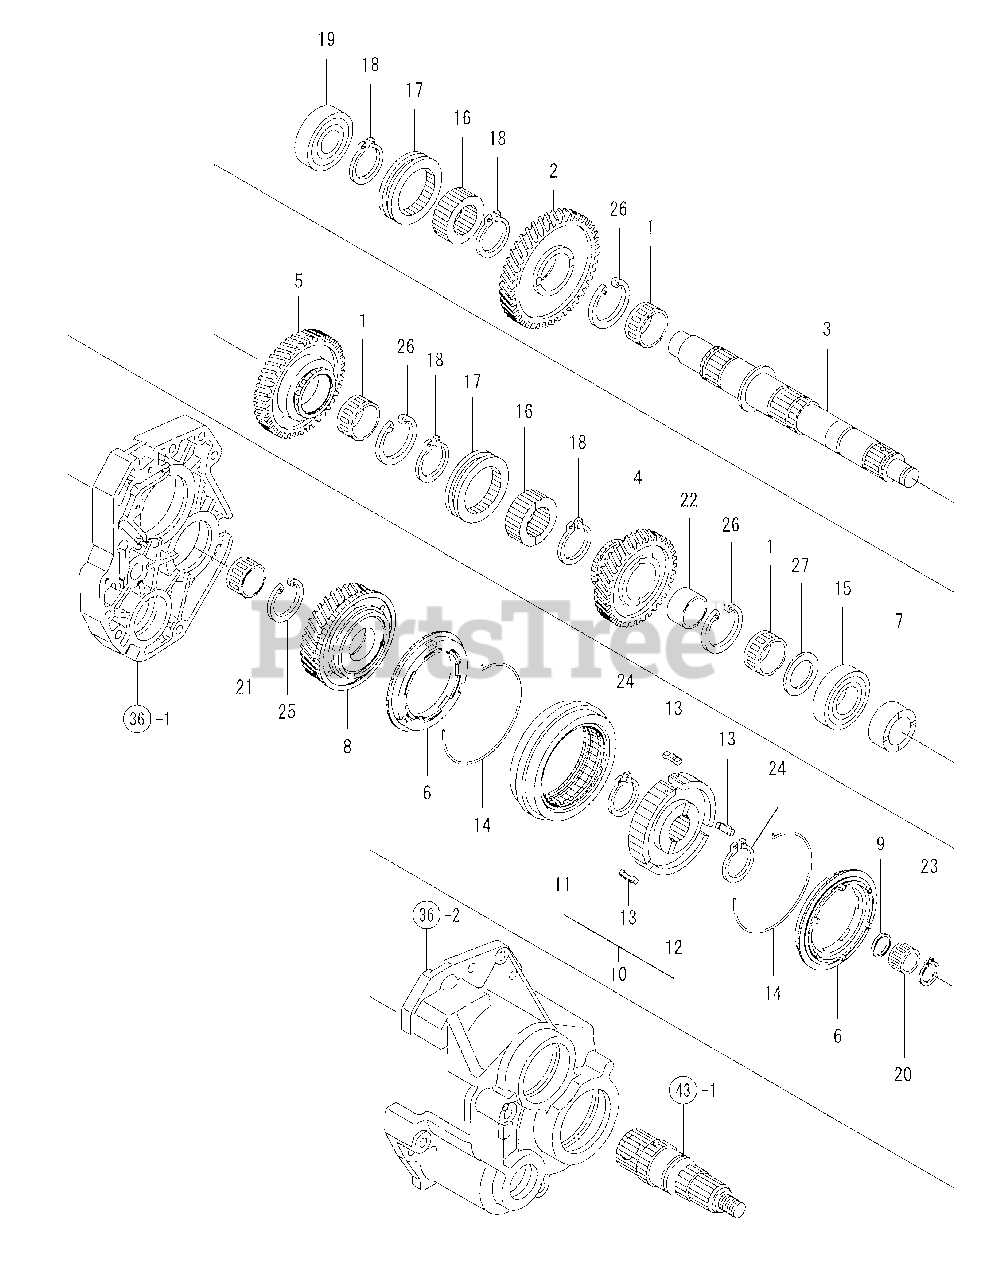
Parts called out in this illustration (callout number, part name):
1	NEEDLE BEARING
6	RING SET, PISTON
7	COLLAR 30X45X20
9	COLLAR 20X45X3.5
10	SLIDER ASSY, SYNCHRO
11	SLIDER,SYNCHRO
16	COLLAR, SPLING
20	NEEDLE 20*26*17
21	NEEDLE BEARING
22	COLLAR 30X35X20
27	WASHER 30.3X45X3
